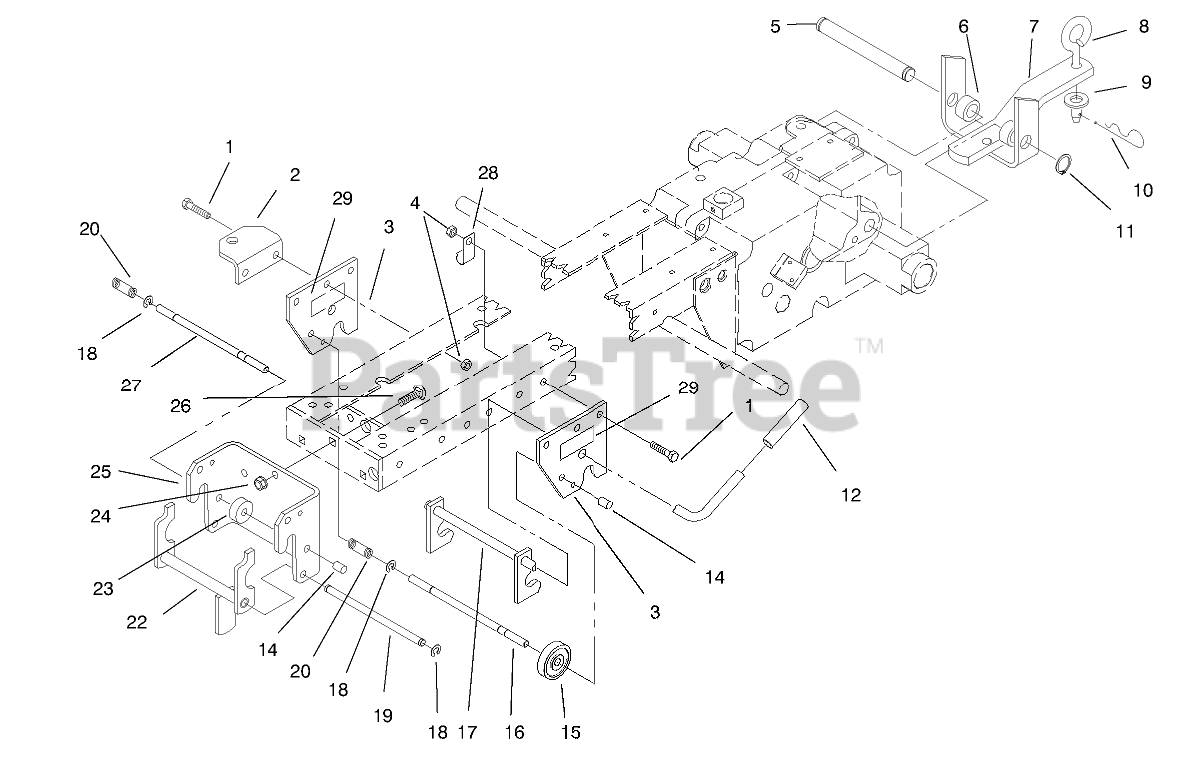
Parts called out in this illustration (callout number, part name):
1	SCREW-HH
2	SUPPORT
3	PLATE-HITCH
5	PIN-STATIONARY HITCH
6	SPACER
7	Hitch ASM
8	PIN-TOOL
9	WASHER-FLAT
10	PIN-HAIR
11	E-RING
12	GRIP
14	CAP-ROD, PLUNGER
16	ROD-LOCK
17	MID HITCH ASM
18	RING-RETAINING
19	ROD-LATCH PIVOT
20	SPRING
22	LATCH
24	NUT-LOCK, NI
25	HITCH-FRONT
26	BOLT-CARR
27	ROD-LOCK
28	CLIP
29	DECAL-ATTACH A-MATIC
